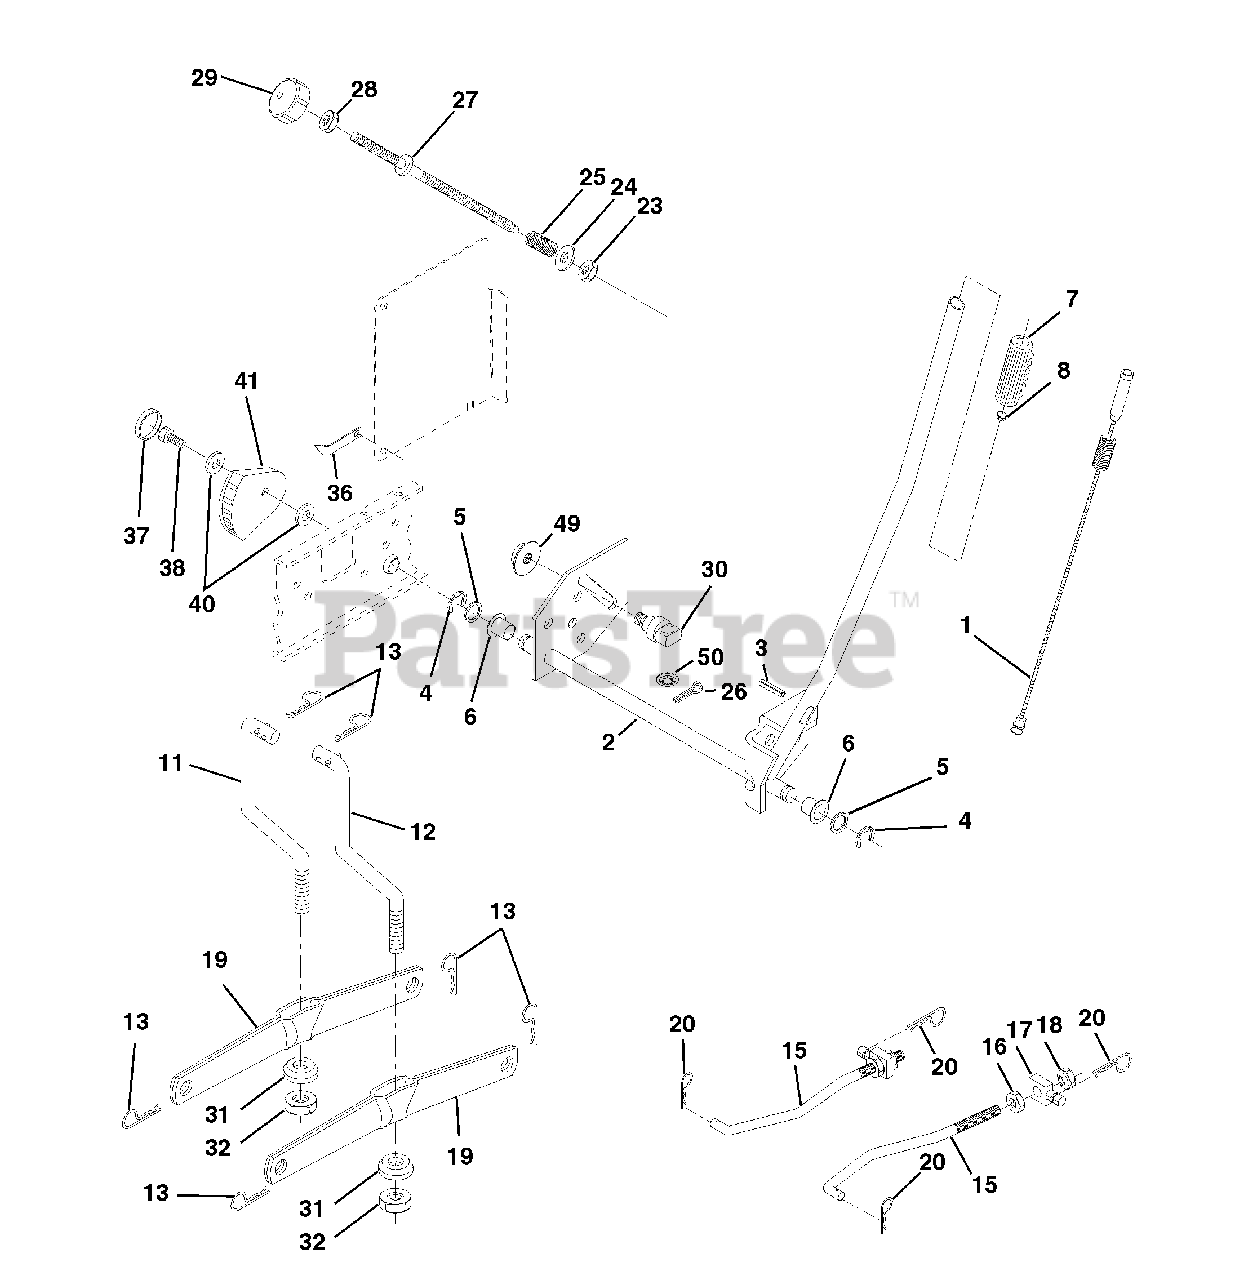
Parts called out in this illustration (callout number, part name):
1	Wire Asm Inner W/plunger
2	Shaft Asm Lift RH w/Inf
3	Pin Groove 1 500 Zinc
4	E Ring #5133-62
5	Washer 21/32 X 1 X 21 Ga
6	Bearing Nylon Blk 629 Id
7	Grip Handle Fluted Blk
8	Button Plunger Black
11	Link Lift LH Fixed Length
12	Link Lift RH Fixed Length
13	Retainer Spring
15	Link Front
16	Nut Jam Hex 1/2-13 Unc
17	Trunnion Blk Zinc
18	Nut Lock W/wsh 1/2-13unc
19	Arm Suspension Rear
20	Retainer Spring
23	Nut Special
24	Washer 13/32 X 5/8 X 16 Ga
25	Spring 2-1/8"
26	Pin Cotter 3/32 X 1/2
27	Rod Adj Lift Zinc 7.49 Wrk Lg
28	Nut Hex Jam 3/8-16 Unc
29	Knob Inf 3/8-16 Unc Blk W/sym
30	Trunnion Infin Height
31	Bearing Pvt Lift Spherical
32	Nut Crownlock 3/8 - 24
36	Pointer Height Indicator
37	Plug Hole Blk 1.485/1.515 Dia.
38	Screw Thdrol 5/16-18 x 3/4
40	Washer 11/32 x 1-1/2 10 Ga.
41	Indicator Height STLT
49	Nut Hex Flange Lock
50	Nut Phos & Oil
